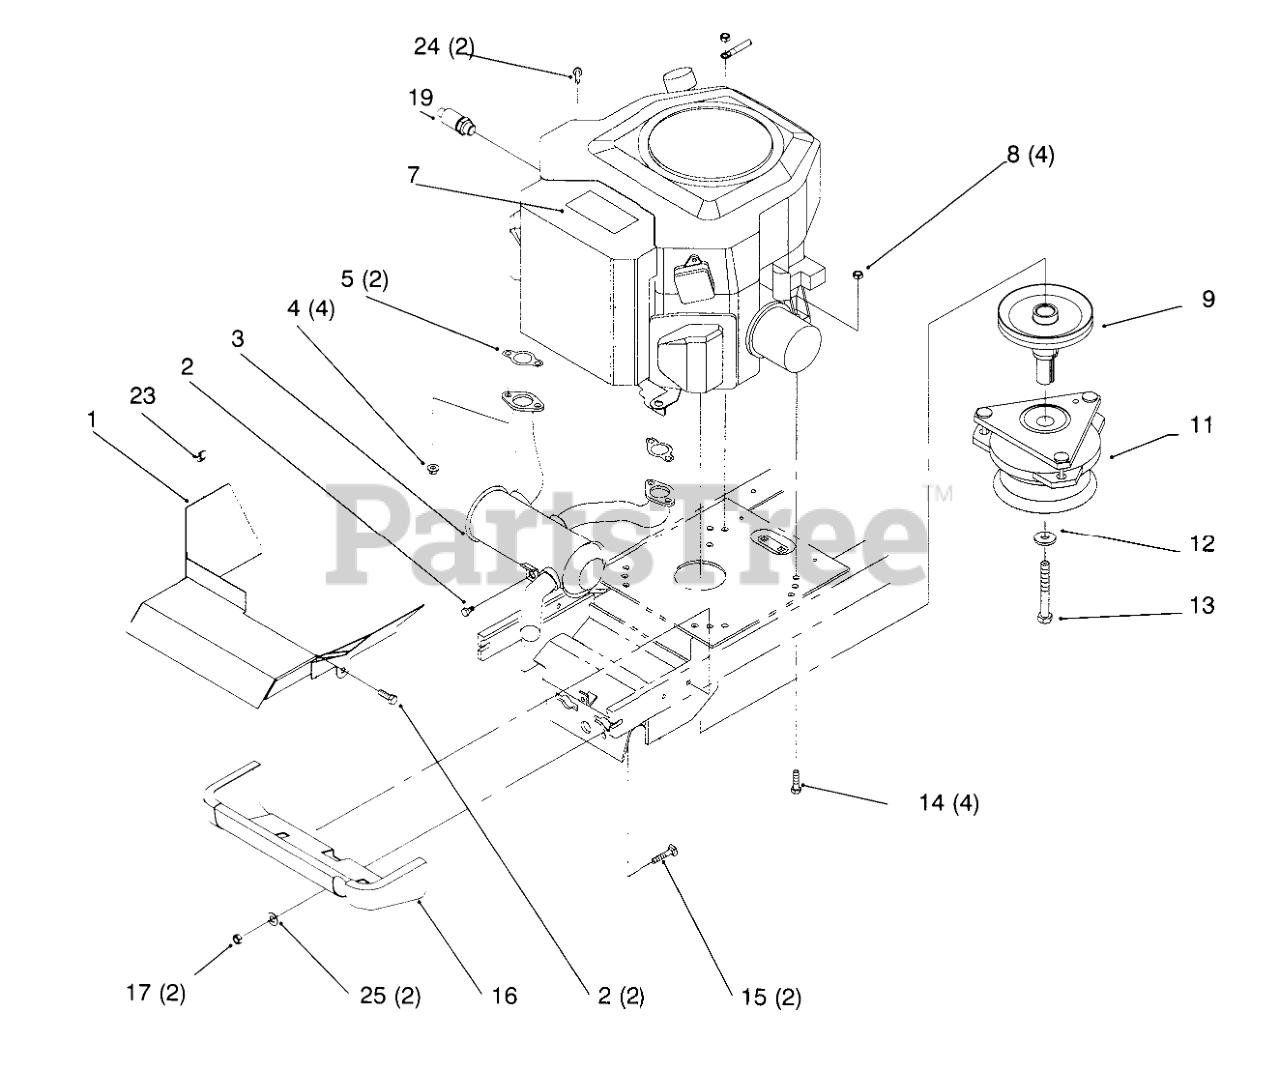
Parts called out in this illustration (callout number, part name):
1	SHIELD-MUF WA TWIN (BLACK)
2	SCREW
3	Muffler
4	NUT-HF
5	GASKET-EXHAUST
7	DECAL - ENGINE
8	NUT-LOCK, NI
9	PULLEY-ENGINE
11	CLUTCH - ELEC PTO
12	WASHER
13	SCREW-HH
14	SCREW-HH
15	SCREW-CARR
16	Shield-Muffler
17	NUT-LOCK, NI
19	VALVE-DRAIN, OIL
23	CLIP-RETAINER, WIRE
24	SCREW-PPH
25	WASHER-FLAT
